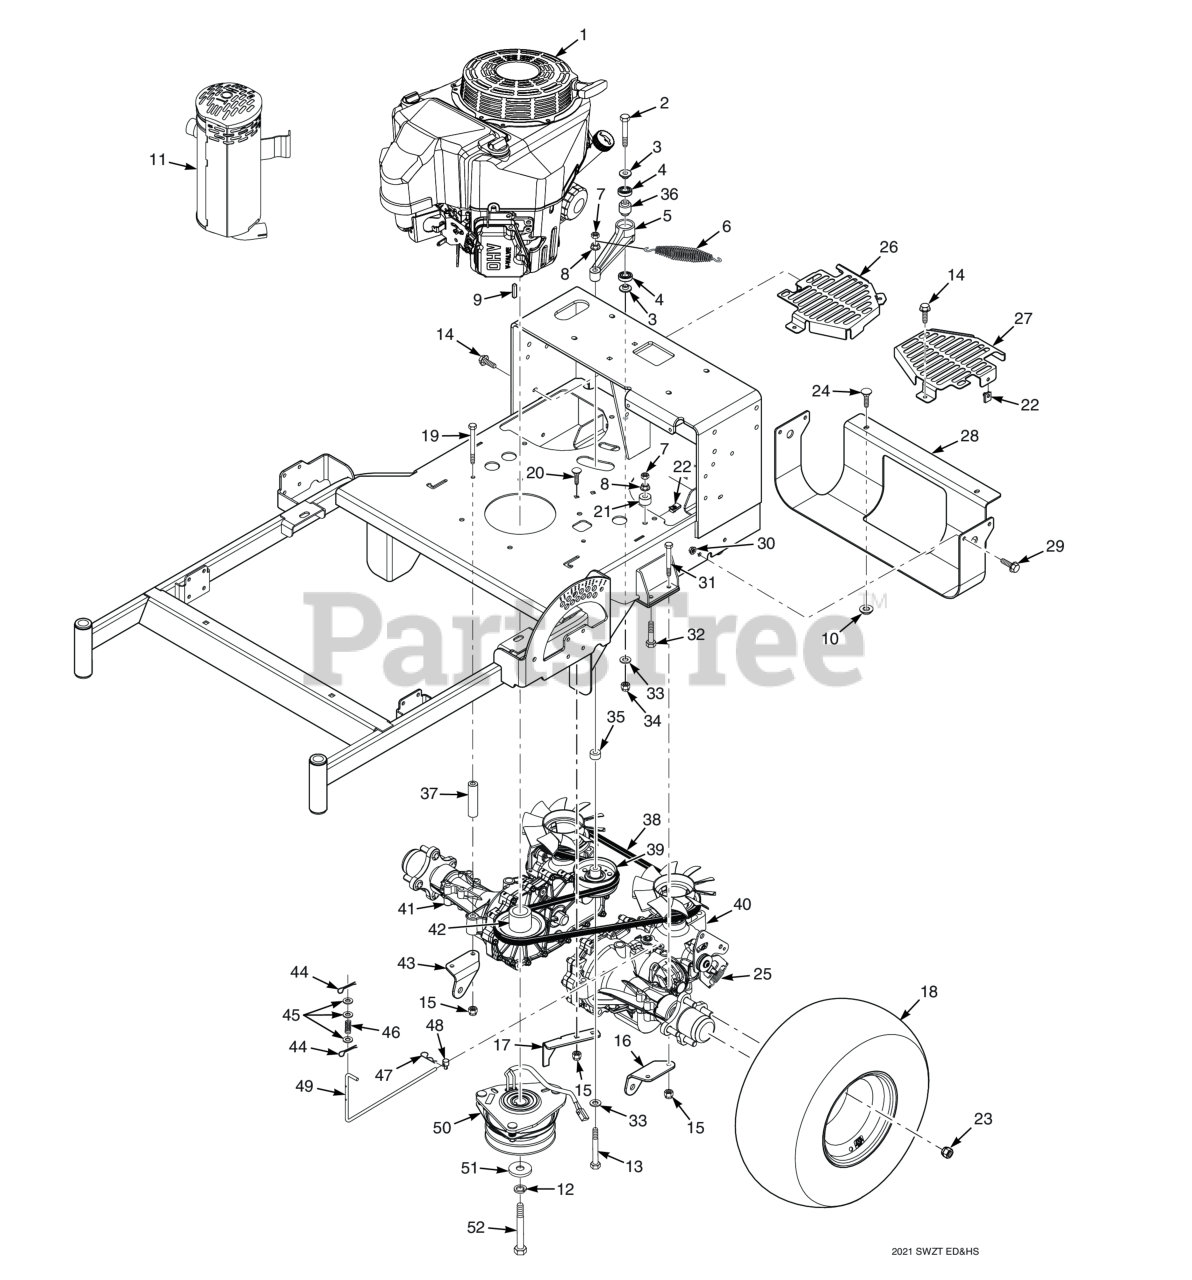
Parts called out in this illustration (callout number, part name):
1	Engine, Kawasaki 14FS (FS481V)
2	Bolt, Hex Head 3/8-16 x 3" - 52"
3	Spacer, Controls
4	BEARINGS, BALL, NEUTRAL RETURN
5	Trans. Idler Arm Assy. (Includes 24, 79)
6	Spring, Transmission Idler
7	Bolt, Hex Head 3/8-16 x 1" Ser. Flg.
8	NUT, 3/8-16 SERRATED FLANGE HEX HEAD
9	KEY, 1/4 X 1/4 X 2-1/2"
10	Nut, Push-On 5/16-18
11	Muffler, Kawasaki (FS481, FS541, FS600)
12	Lockwasher, 7/16� Spring
13	Capscrew, Hex Head 3/8-16 x 3-3/4"
14	Bolt, Serrated Flange Hex Head 1/4 x 20 x 3/4"
15	HEX NUT, ELASTIC STOP LOCK, 5/16-18
16	Pusharm Mount Bracket, LH
17	Bracket, Anti-Rotation
18	Wheel Assembly 18 x 6.5-8 (36" Only)
19	Bolt, Hex Head 5/16-18 x 6-1/2"
20	Bolt, Carriage 5/16-18x1" (large frame units only)
21	SPACER, J PULL ROD
22	Bolt, Hex Head 3/8-16 x 1"
23	Wheel Nut, 1/2-20 x 13/16
24	Bolt, 5/16-18 x .75 RHSN Carriage
25	Spring, RTN
26	Fan Cover, RH
27	Fan Cover, LH
28	Skid Plate
29	Capscrew, 5/16-18 x .75 Serrated Flange Hex Head
30	Nut, Serrated Flange 5/16-18 (Right Front Engine Mounting, Briggs and Kohler Only)
31	Bolt, Hex Head 5/16-18 x 3.00"
32	Bolt, Hex Head 3/8-16 x 2-1/2" 1.5 Thread Grd.8
33	Flatwasher, 3/8 (.391 x .938 x .105 HD) Grade 8
34	HEX NUT, ELASTIC STOP LOCK, 3/8-16
35	Spacer, Idler Pulley - SFZ61
36	Spacer, Bearing
37	Spacer, Axle
38	Belt, Transmission Drive
39	Pulley, 3-1/2" Dia.
40	Transaxle Assy., (ZH-GMCC-SLUB-1MTX)
41	Transaxle Assy., (ZH-KMCC-3LUC-1MTX)
42	Pulley, 4-1/2" Dia. - 1" Bore
43	Pusharm Mount Bracket, RH
44	COTTER PIN, 3/32 X 1"
45	Flatwasher, 1/4" (.312 x .750 x .065")
46	Spring, Dump Valve Link
47	Pin, Rue Cotter 3/8" Diameter
48	Joint, Swivel
49	Link, Dump Valve
50	Electric Clutch Assembly
51	Flatwasher, 7/16-.469 x 1.75 x .25 (48, 52)
52	Bolt, Hex Head 7/16-20 x 3" w/t Patch
